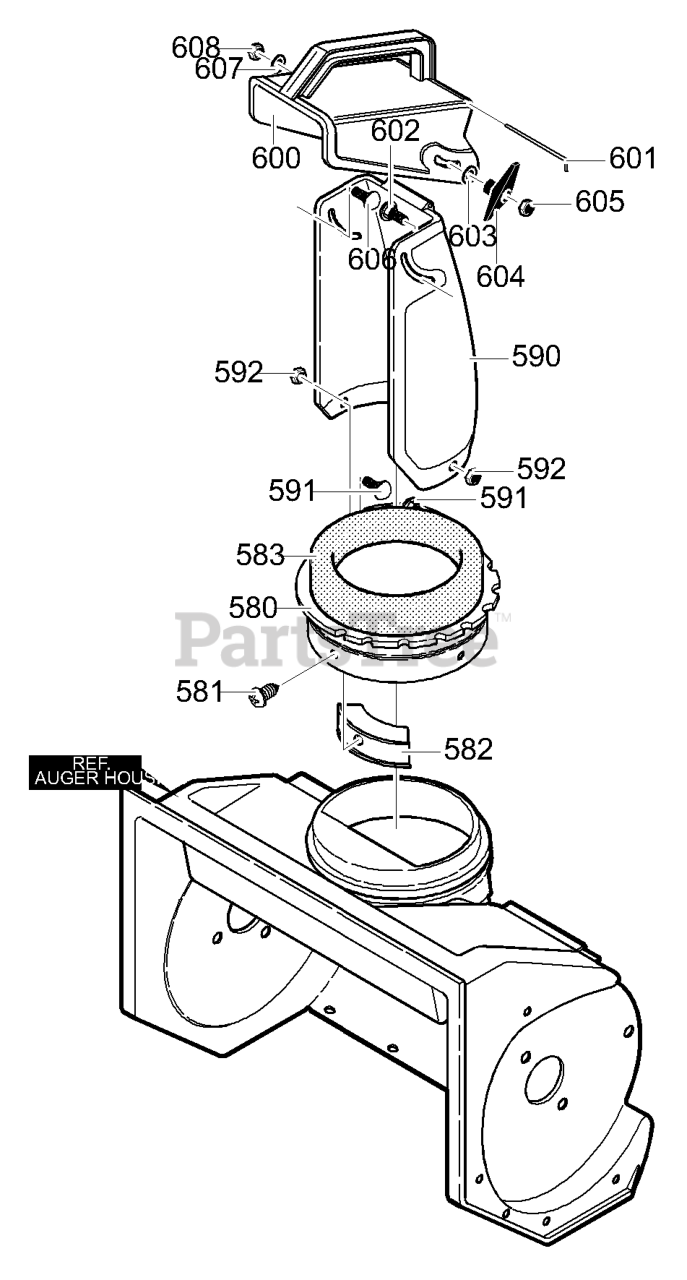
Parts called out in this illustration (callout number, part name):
580	RING, CHUTE
581	SCREW, #10X.50
582	GUIDE, CHUTE
583	DONUT FOAM
590	CHUTE, LOWER
591	SCREW 1/4-20X.50
592	NUT, 1/4-20
600	CHUTE, UPPER
601	WIRE, CHUTE HINGE
602	BOLT, 5/16-18X1.25 CARR.
603	WASHER, FLAT .349X.69X.066
604	KNOB, T
605	NUT, 5/16-18
606	SCREW, 5/16-18 x 0.75
607	WASHER, FLAT .349X.69X.066
608	NUT, 5/16-18
